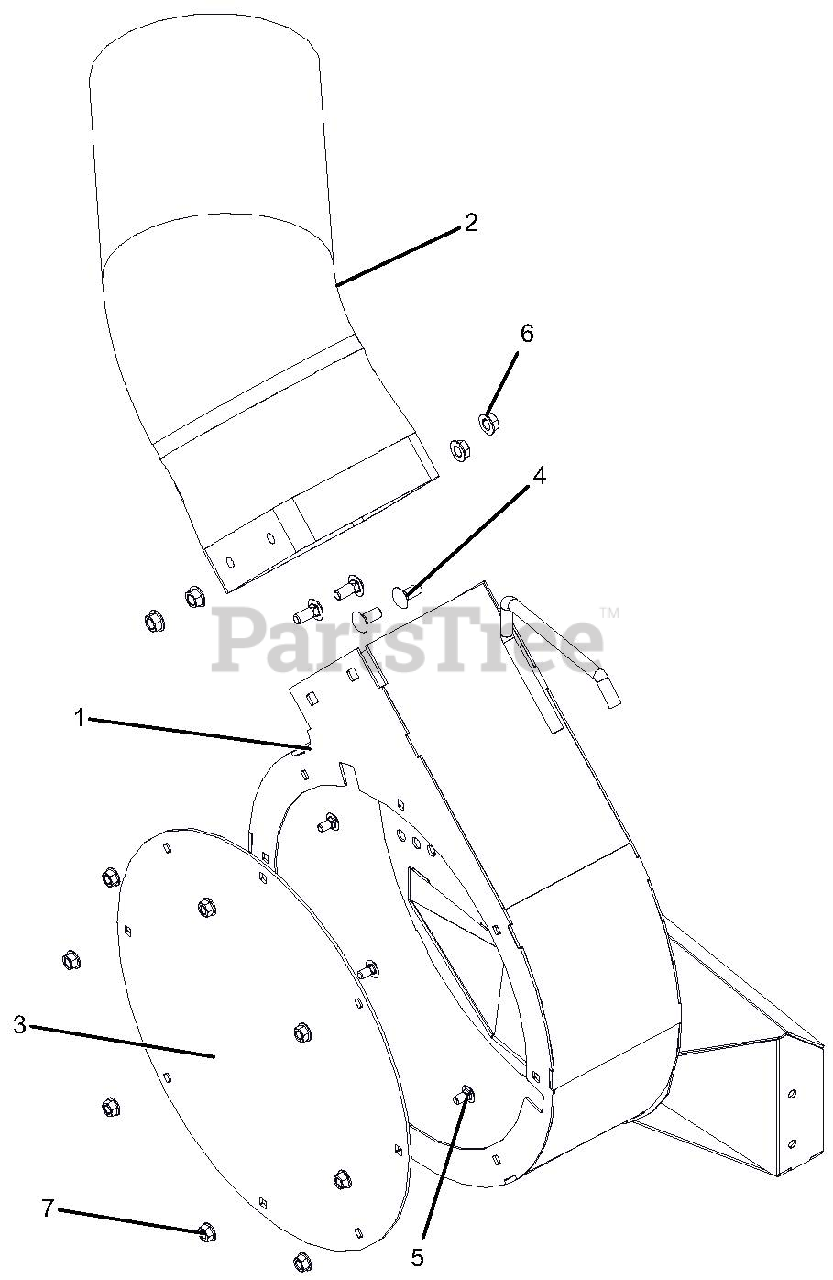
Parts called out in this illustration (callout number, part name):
1	HSG, BLOWER -W/DECALS
2	ADAPTER-HOSE 52/60"
3	COVER, BLOWER HOUSING METAL
4	@BLT-RDHDSQNK .31-18X.75 G5YZ
5	@BLT-RDHDSQNK .25-20X.50 G5YZ
6	@NUT-LK-TOP-FLG .31-18 YWZC
7	@NUT-LK-TOP-FLG .25-20 YWZC
